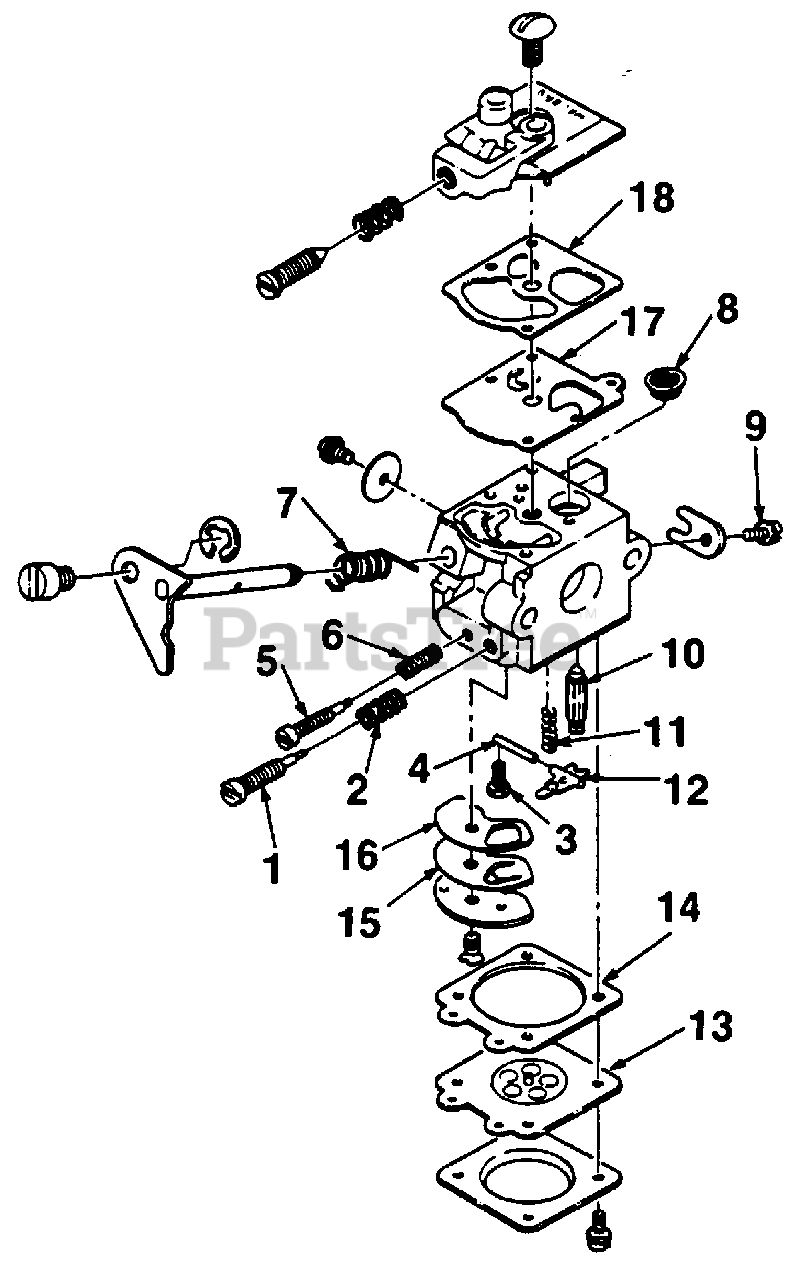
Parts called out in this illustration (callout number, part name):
1	Repair Kit
2	Repair Kit
3	Repair Kit
4	Repair Kit
5	Repair Kit
6	Repair Kit
7	Repair Kit
8	Repair Kit
9	Repair Kit
10	Repair Kit
11	Repair Kit
12	Repair Kit
13	Repair Kit
14	Repair Kit
15	Repair Kit
16	Repair Kit
17	Repair Kit
18	Repair Kit
